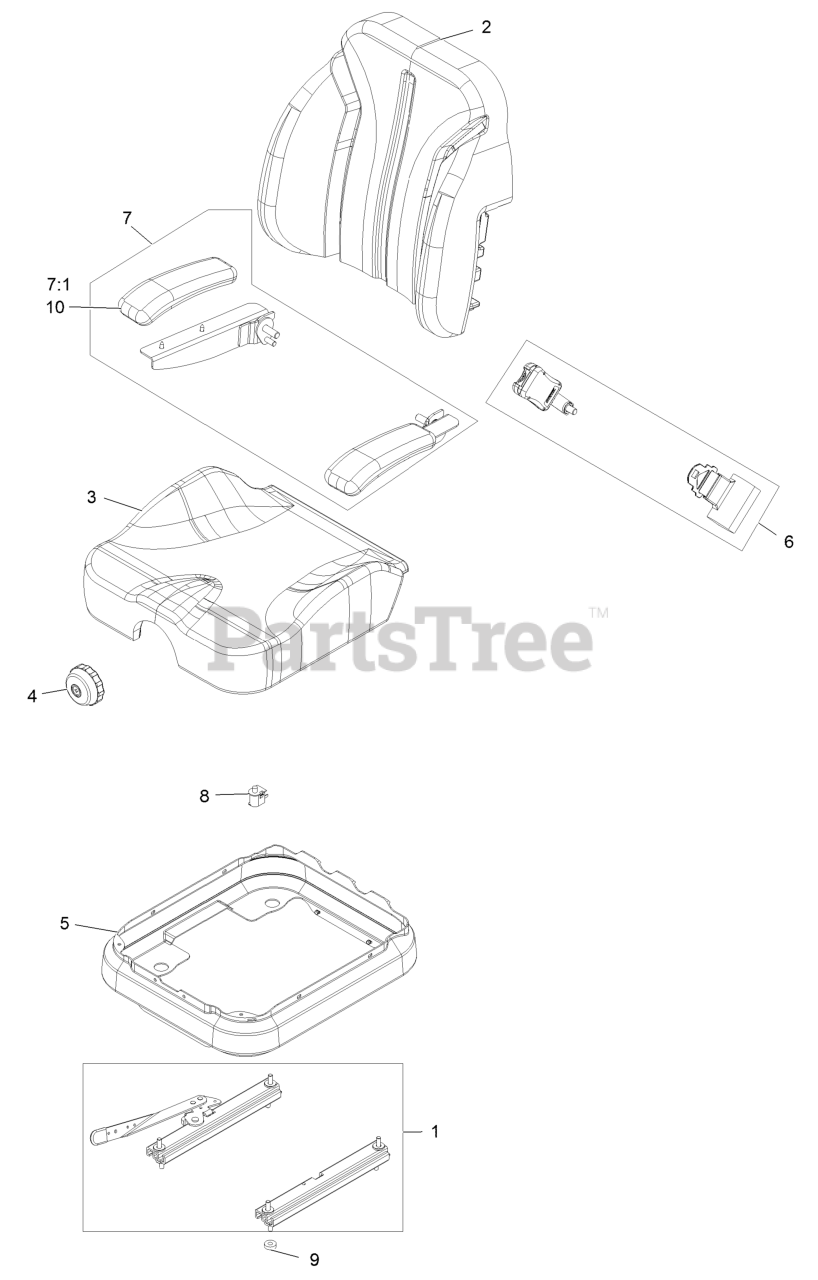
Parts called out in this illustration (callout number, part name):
1	Tracks-4" Travel
2	Cover-Seat Back Svc
3	Cover-Seat Bottom Svc
4	Knob-Adjuster
5	Bellows-Seat
6	Kit-Seat Belt
7	Armrest Kit
7:1	Cushion-Rest, Arm
9	Spacer-Pin, Mounting
10	Cushion-Rest, Arm
